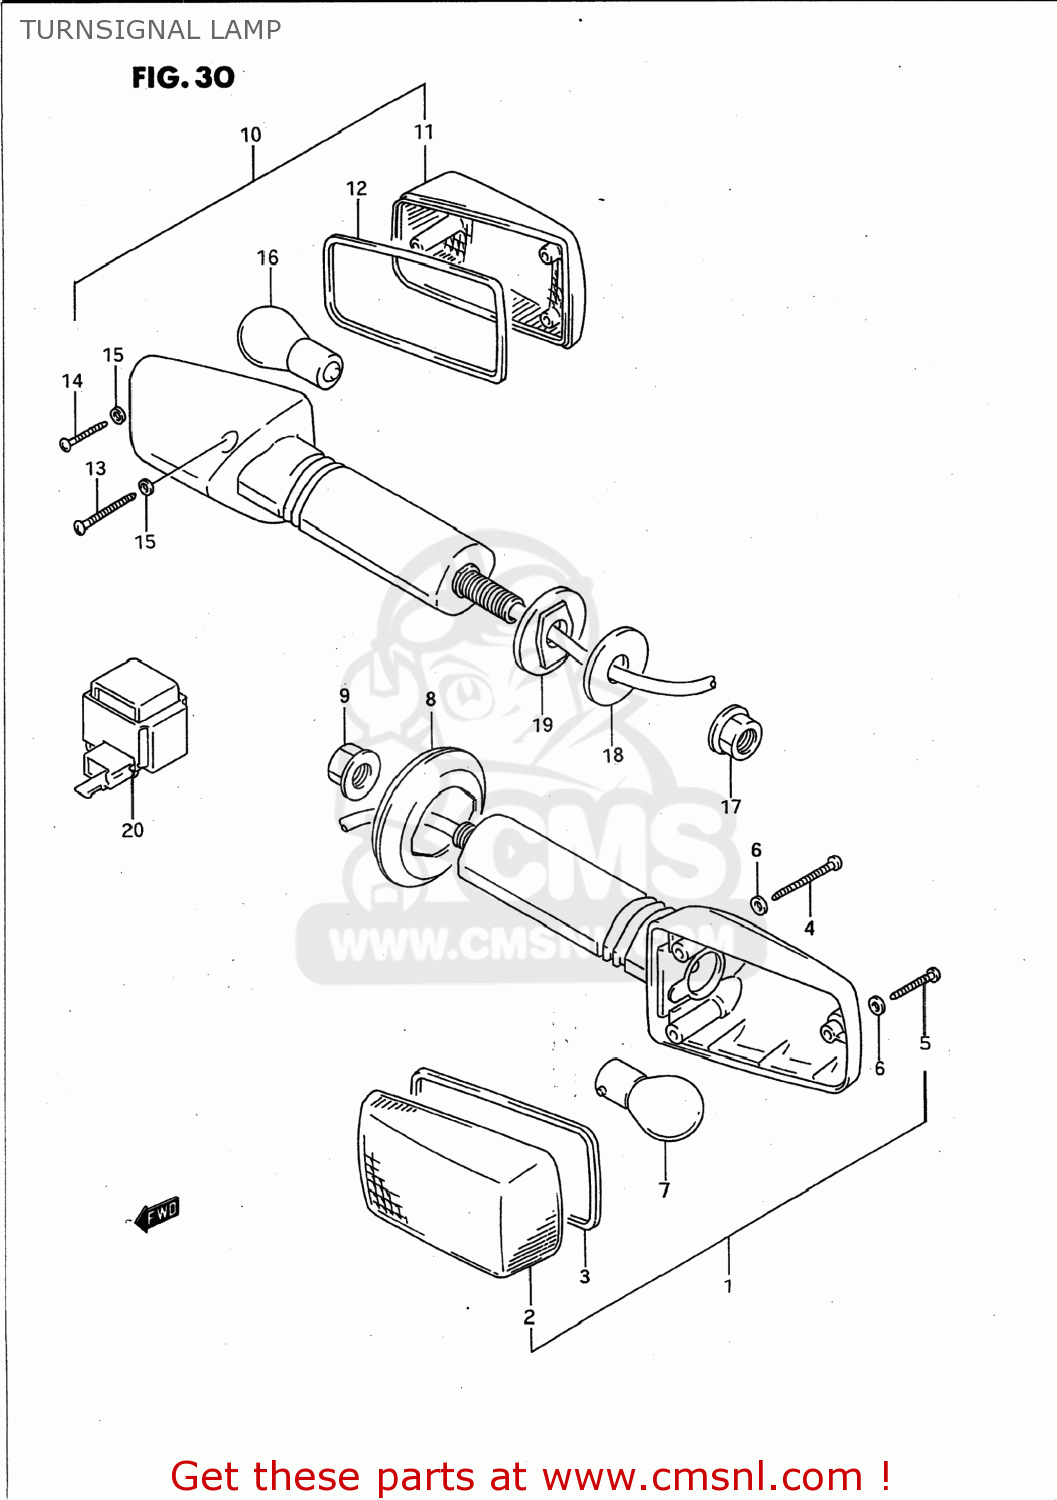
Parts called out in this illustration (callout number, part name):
1	LAMP ASSY,FR TURN SIGNAL
2	LENS
3	GASKET (NAS)
4	SCREW(3X30)
5	SCREW
6	GASKET (NAS)
7	BULB(12V21W)
8	GROMMET
9	NUT
10	LAMP ASSY,RR TURNSIGNAL
11	LENS
12	GASKET (NAS)
13	SCREW(3X30)
14	SCREW
15	GASKET (NAS)
16	BULB(12V21W)
17	NUT
18	WASHER(10.5X30X3.2)
19	SPACER,RR TURNSIGNAL
20	RELAY,TURN SIGNAL
